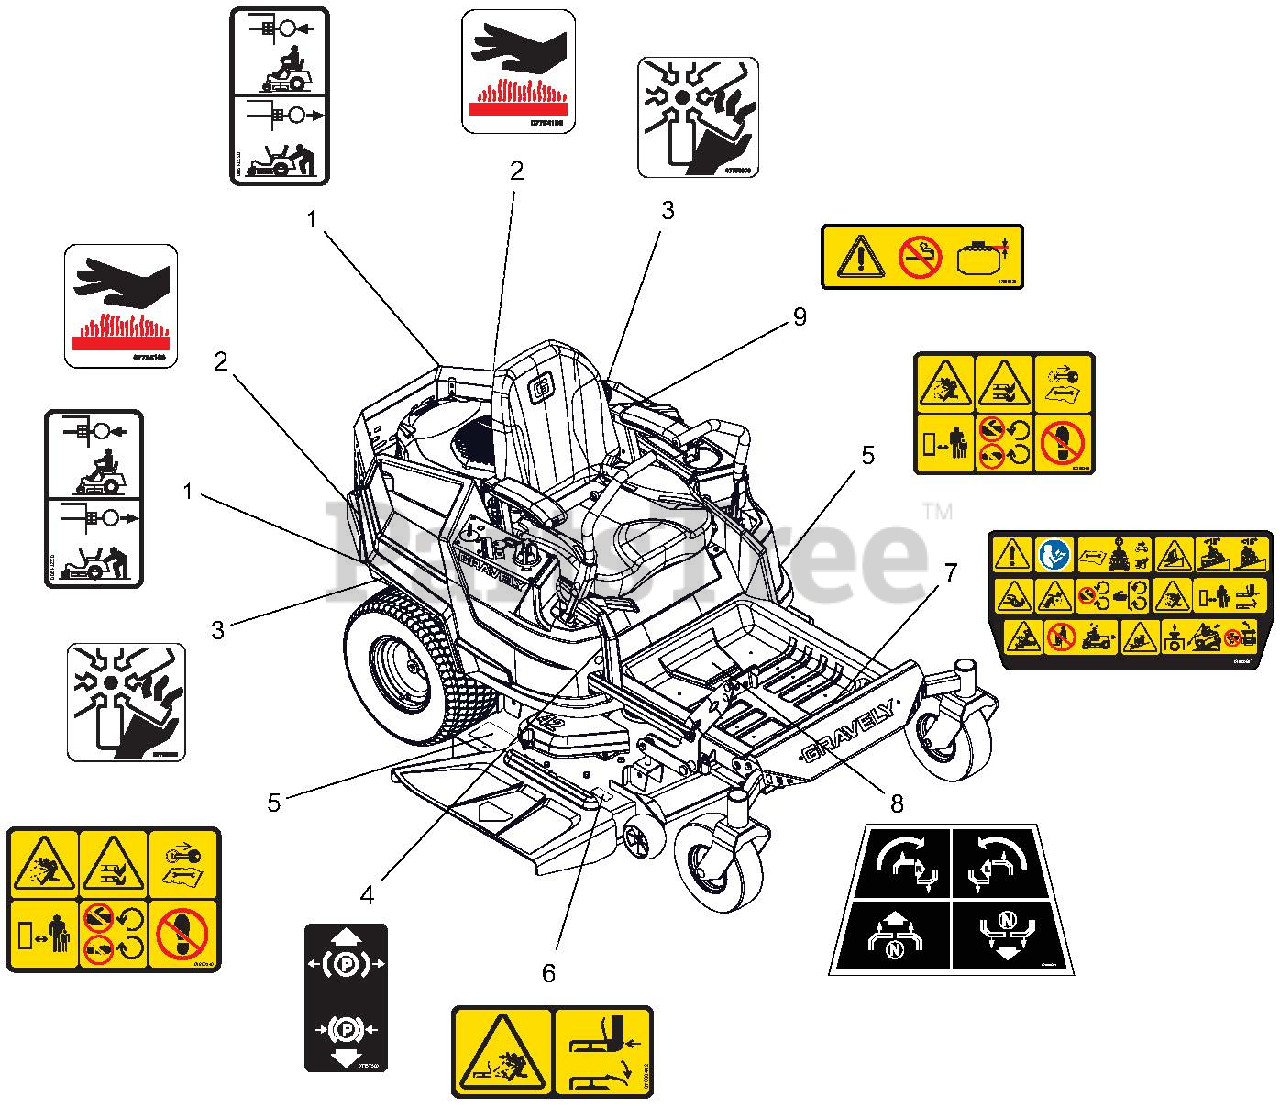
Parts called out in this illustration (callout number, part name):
1	DECAL, TRANSMISSION DISCONNECT
2	DECAL, HOT SURFACE
3	DECAL, DANGER FAN
4	DECAL, PARKING BRAKE LEVER
5	DECAL, SAFETY - MOWER DECK
6	DECAL, SAFETY - DECK GUARDING
7	DECAL, MAIN SAFETY
8	DECAL, STEERING
9	DECAL-FUEL, WARNING
